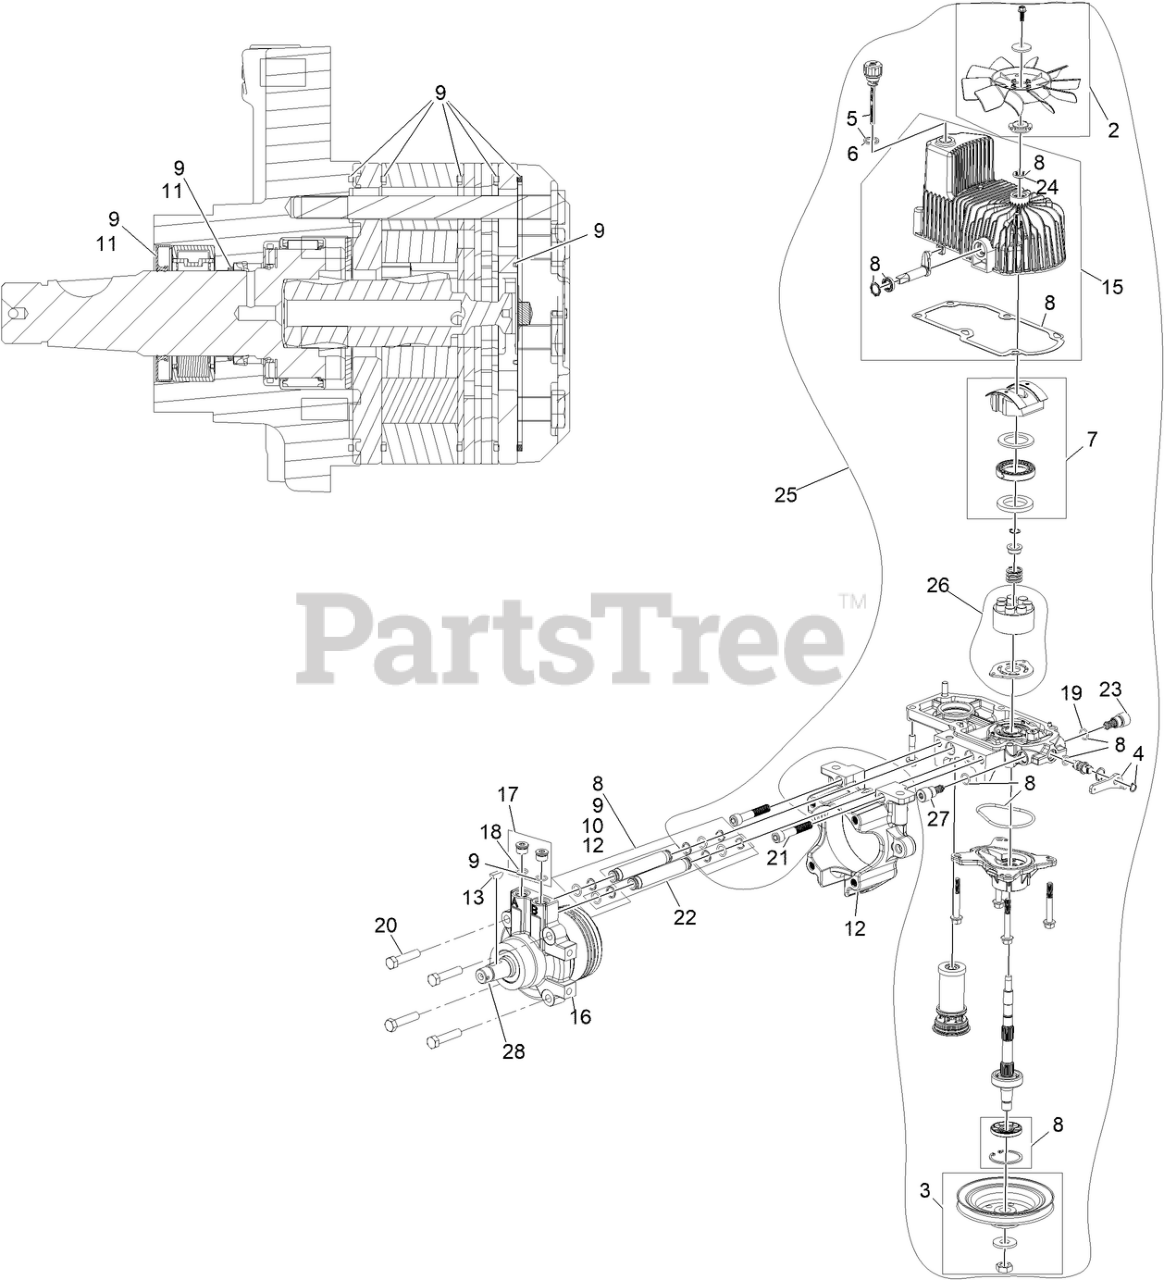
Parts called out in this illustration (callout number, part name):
2	FAN KIT
3	PULLEY KIT
4	HANDLE-BYPASS VALVE, HYDRO
5	DIPSTICK-HYDRO W/GASKET
6	GASKET-DIPSTICK, HYDRO
7	SWASH BLOCK KIT
8	PUMP SEAL KIT
9	MOTOR SEAL KIT
10	TUBE SEAL KIT
11	OUTPUT SHAFT SEAL KIT
12	NOSE CUP-UHT
13	KEY-WOODRUFF
15	HOUSING-HYDRO, LH
16	MOTOR-HYDRAULIC, LH 280CC
17	MAGNETIC PLUGS SERVICE KIT
18	O-RING
19	O-RING-CHECK VALVE
20	SCREW HH
21	SCREW-HSH
22	HYDRAULIC TUBE KIT
23	SHOCK VALVE, 16CC HYDRO
24	SEAL-FAN DRIVE
25	16CC LH PUMP SECTION KIT
26	16CC LH ROTATING GRP KIT
27	SHOCK VALVE ORIFICED 3300
28	OUTPUT SHAFT- TL UHT MOTOR
99	PULLER-PULLEY
